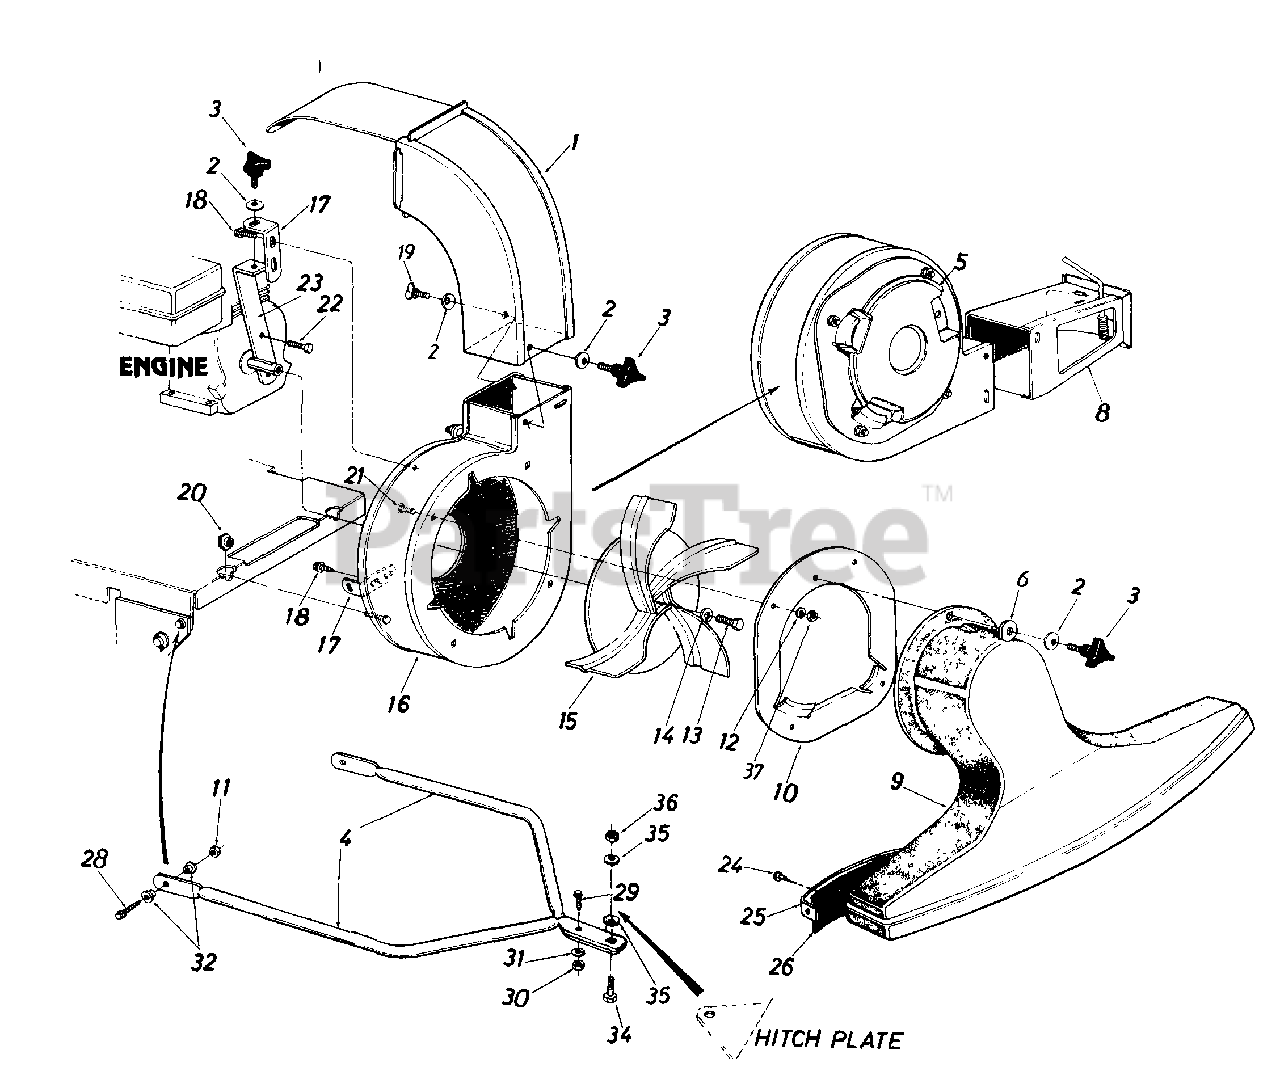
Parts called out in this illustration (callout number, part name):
3	Hand Knob
6	Fl-Wash..344" I.D. x 1.125" O.D.
12	L-Wash. 5/16" I.D."
13	Hex Bolt 3/8-24 x 1.25" Lg.
14	L-Wash. 3/8" I.D. H.D.
15	Air Vane Plate Ass'y. w/Pulley
19	Thumb Screw 5/16-18
20	Hex Shoulder Nut.50 I.D.
21	Carriage Bolt 5/16-18 x .62"
22	Hex Locking Bolt 5/16-24 x .75" Lg.
28	Hex Bolt 5/16-18 x 1.00" Lg.
29	Truss Mach. Scr. 1/4-20 x .75"
30	Hex Nut 1/4-20 Thd.
31	L-Wash. 1/4" I.D.
32	Shoulder Spacer
34	Shld. Bolt .496 Dia.
35	Belleville Wash..39" I.D x 1.12" OD
36	Hex Jam L-Nut 3/8-26 Thd.
37	Hex Nut 5/16-18 Thd. (Gr 5)
